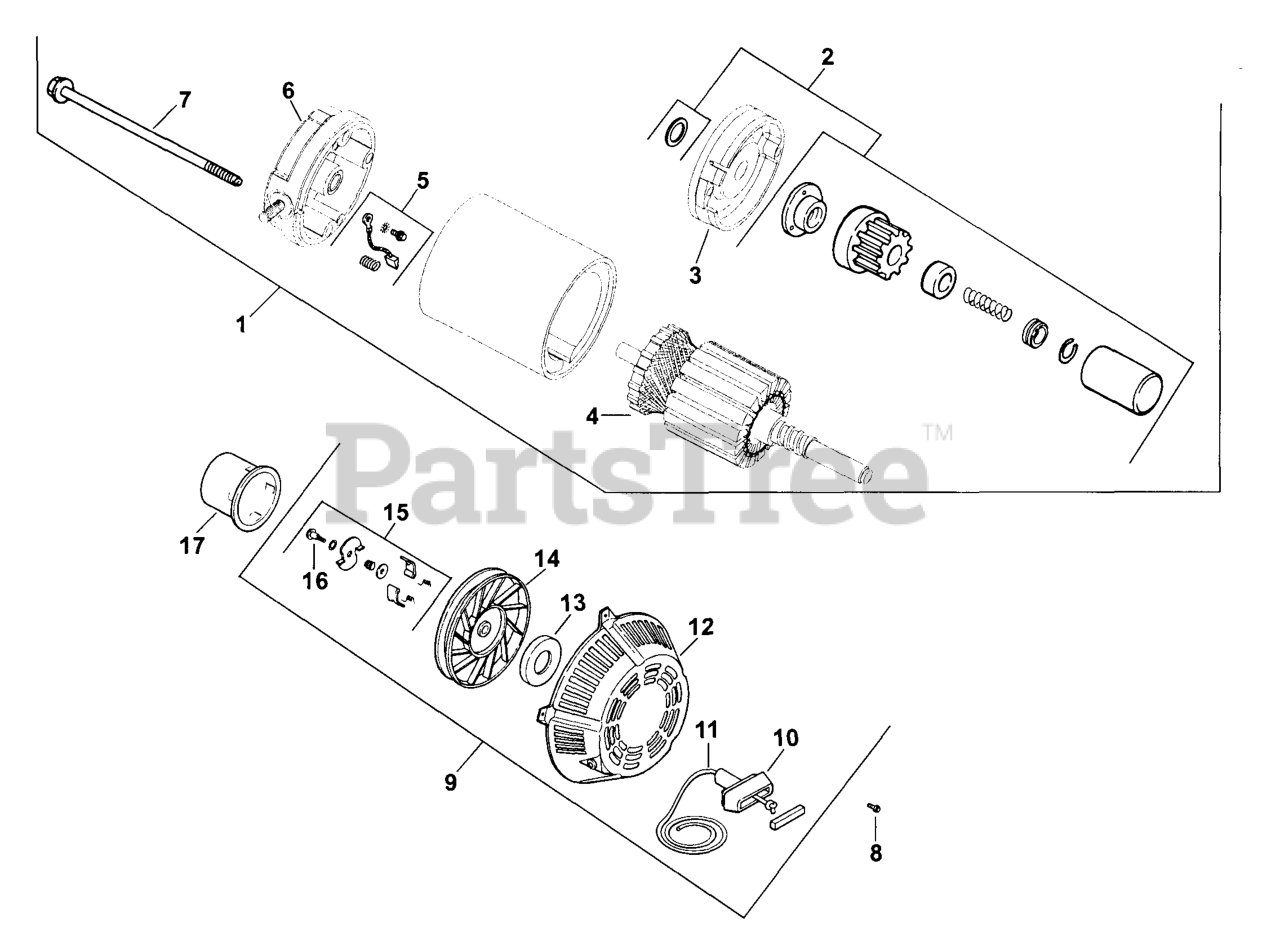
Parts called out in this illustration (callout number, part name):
1	KIT, STARTER - (#DSC)
2	KIT, DRIVE
3	CAP, DRIVE
4	ARMATURE ASSY - DISCONTINUED
5	KIT, BRUSH & SPRING - DISCONTINUED
6	CAP, COMMUTATOR (#DSC)
7	THRU BOLT
